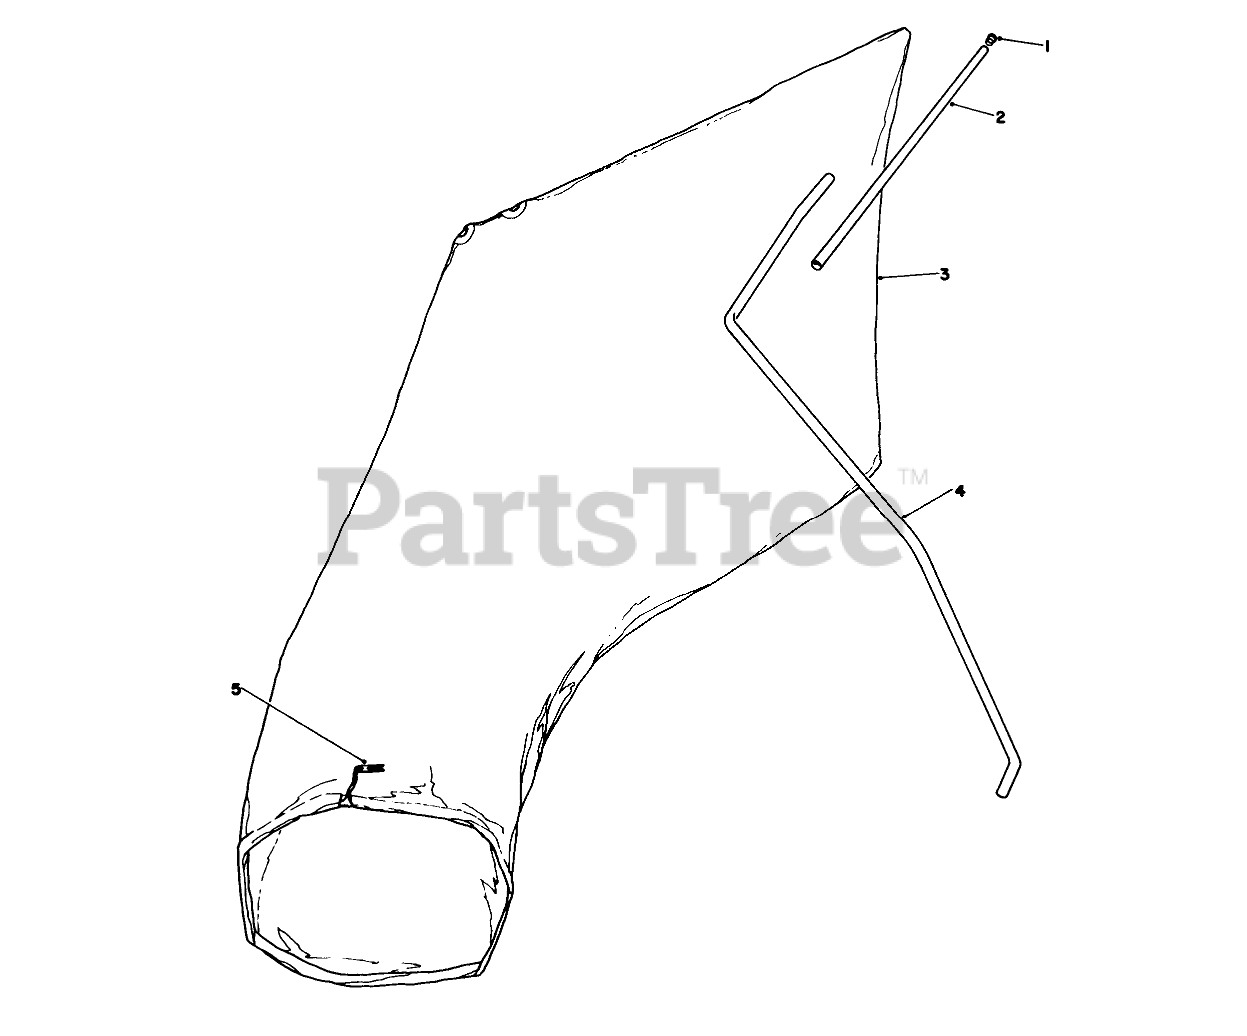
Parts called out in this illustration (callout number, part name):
2	BAG HANGER TUBE
3	Bag (Incl. Ref. #5)
4	HANGER ROD
5	BAG CORD FASTENER
